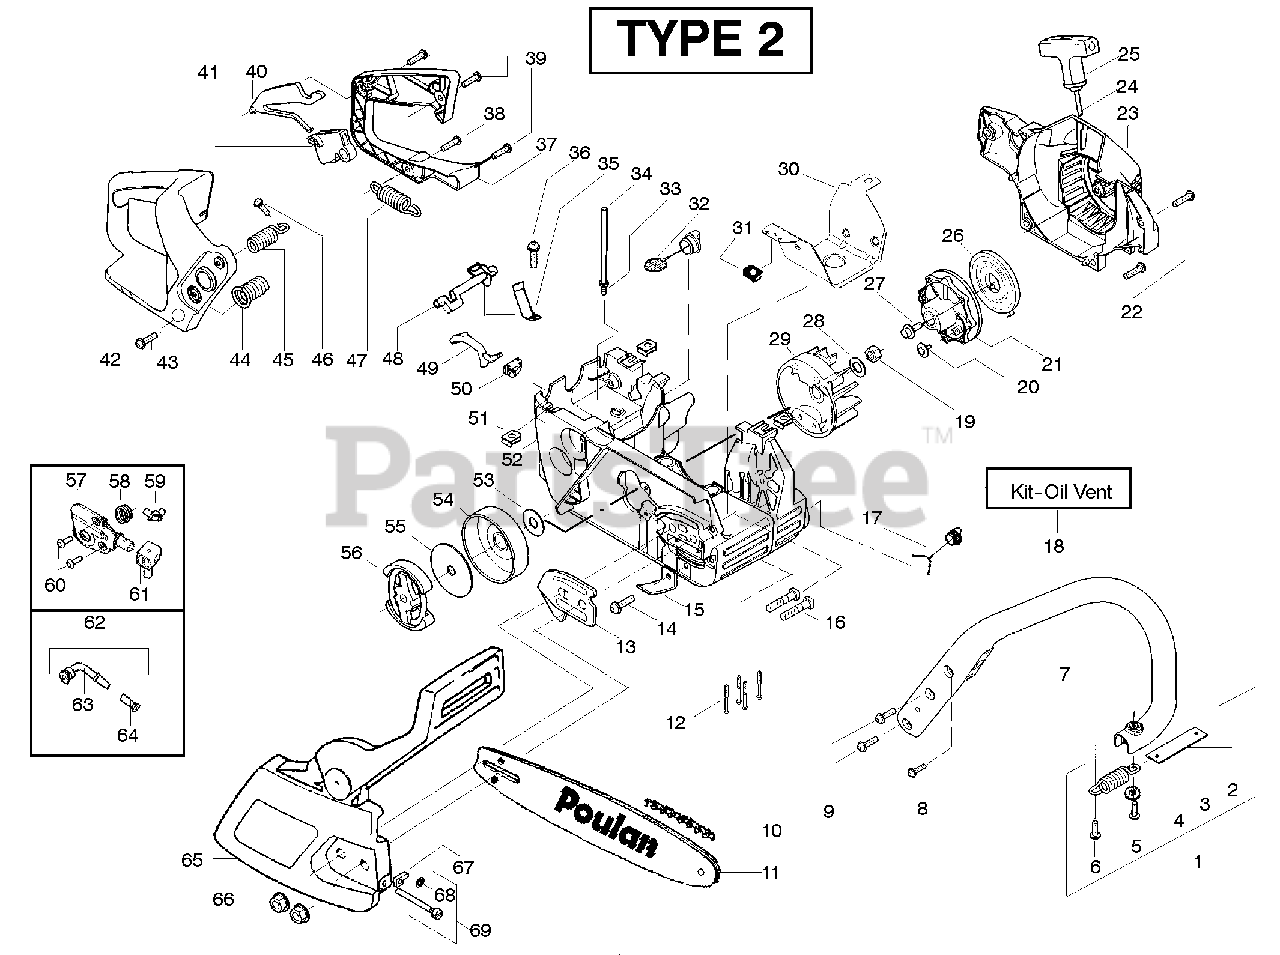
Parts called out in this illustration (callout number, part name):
1	Assy.-Isolator
2	Limiter Strap
3	Spring-Isolator
4	Washer
7	Front Handle
10	Chain -18"
11	Bar - 18"
13	Plate-Bar Mount.
15	Chain Catcher
16	Bolt-Bar
17	Assy-Oil Cap
18	Kit-Oil Vent
19	Nut-Flywheel
21	Starter Pulley
23	Housing-Fan
24	Kit - Rope
25	Handle-Starter
26	Spring-Recoil
28	Washer-Flywheel
29	Assy-Flywheel
30	Shield - Heat
31	Clip - "U"
32	Assy-Fuel Cap
33	Fitting-fuel line
34	Kit-Fuel line (large)
35	Spring-Switch
37	Cover-Rear Handle
40	Throttle Lockout
41	Trigger-Throttle
42	Handle - Rear
43	Screw
44	Assy Isolator-lower
45	Kit-Isolator (Upper)
47	Spring-Isolator
48	Lever-Switch
49	Lever-Choke
50	Grommet-Knob
51	Nut-"U"-Type
52	Kit-Chassis Assy. Fuel lines and caps
53	Washer-Thrust
54	Assy.-Clutch Drum w/bearing
55	Washer-Clutch
56	Assy. Clutch
57	Kit - Oil Pump
58	Gear-Worm Spring
59	Elbow-Oil Pickup
61	Seal Block
62	Assy-Oil Pick-up
63	Pick-up Oiler
64	Filter-Oil
65	Assy.-Chain Brake
66	Nut-Bar Mounting
67	Pin-Bar Adjust
68	Retainer
69	Kit-Bar Adjusting
